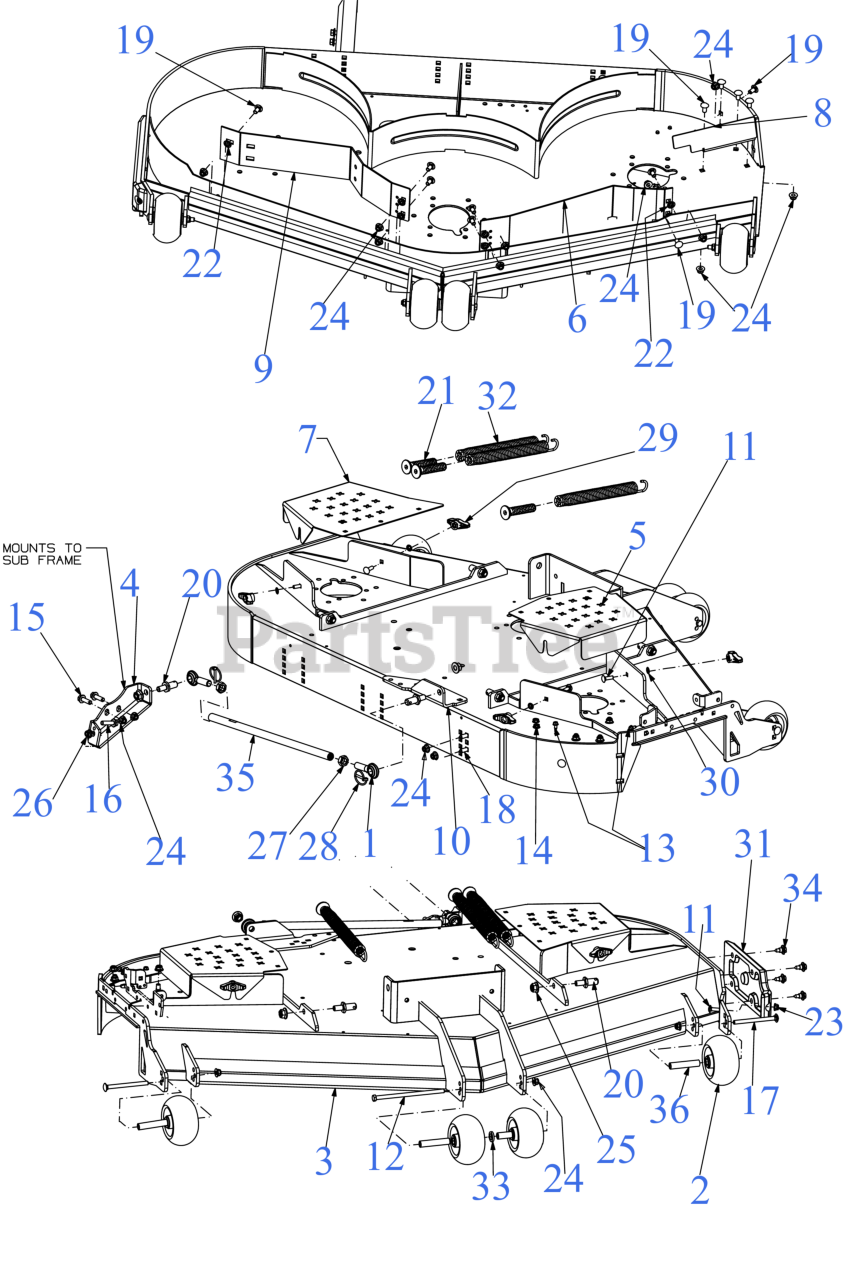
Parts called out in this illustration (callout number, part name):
1	MALE ROD END
2	5" DIA DECK WHEEL COMPLETE
3	60" FAB DECK SHELL
4	STABILIZER MOUNTING BRACKET
5	DECK BELT COVER
6	DECK BAFFLE
7	BELT COVER
9	DECK BAFFLE
10	DECK BELT GUIDE BRACKET
11	CARRIAGE BOLT 5/16-18 x 1.00
12	SCREW 3/8-16 x 7.25 GR5
13	SCREW 1/4-20 X.500
14	SCREW 5/16-18 x .500
15	SCREW 3/8-16 x 1.25 GR5
16	HEX HEAD BOLT (3/8-16:1.50 GR8)
17	CARRIAGE BOLT 3/8-16 x 4.25 GR5
18	CARRIAGE BOLT 3/8-16 x 1.00 GR5
19	CARRIAGE BOLT 3/8-16 x .75
21	SPRING INSERT SCREW
23	FLANGE LOCK NUT 5/16-18
26	LOCK NUT (3/8-16)
27	HEX JAM NUT 5/8-18
28	LYNCH PIN .1875
29	WING KNOB 5/16-18
31	DECK SKID PLATE (LH)
32	EXTENTION SPRING 1.20 x 11.35
33	FLAT WASHER .632X1.00X.16
34	SHOULDER SCREW .43X.29X5/16-18 TT
35	TUBE .565 X .750 X 18.75"LG
36	WHEEL SPACER .38ID x 3.04LG
